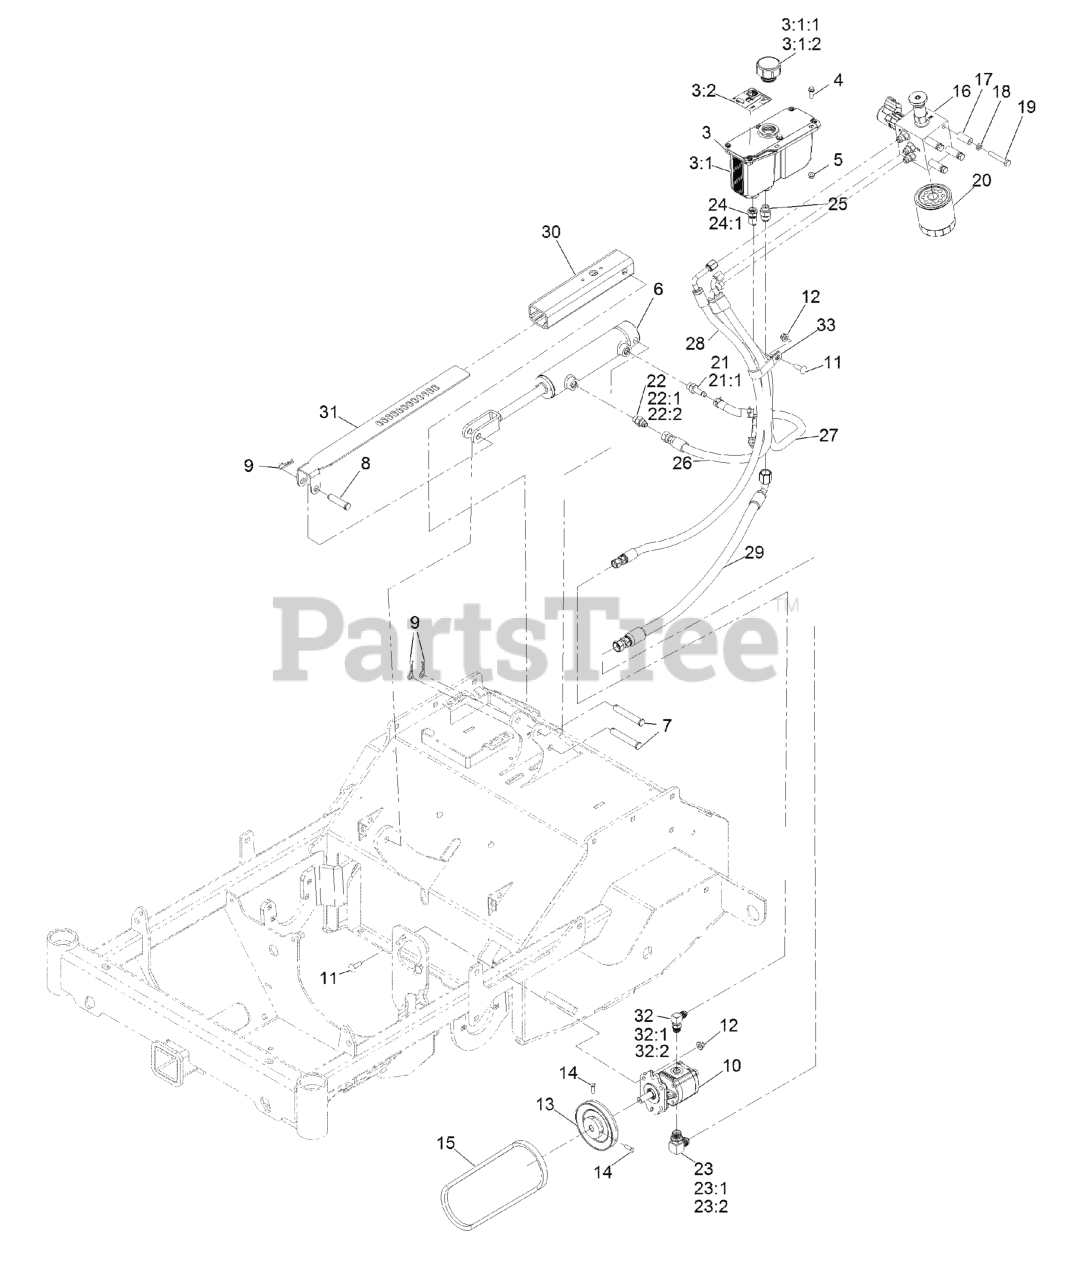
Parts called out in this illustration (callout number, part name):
3	RESERVOIR ASM
3:1	Reservoir-HYD
3:1:1	Cap-Reservoir, HYD
3:1:2	GASKET-CAP
3:2	DECAL-WARNING
4	SCREW-HWH
6	CYLINDER-HYDRAULIC
7	PIN-CLEVIS
8	PIN-CLEVIS
9	PIN-HAIR
10	PUMP-HYDRAULIC
11	SCREW-CARR
12	NUT-HF, NI
14	SCREW-SQH
16	MANIFOLD ASM
18	WASHER-LOCK
19	SCREW-HH
20	FILTER-25 MICRON, BI-DIRECTIONAL
21	ADAPTER-STRAIGHT
21:1	O-RING
22	FITTING-STRAIGHT
22:1	BOSS O-RING
23	FITTING-90 DEG
24	FITTING-BARBED, 45 DEG
24:1	O-RING
25	FITTING-STR
26	HYDRAULIC HOSE ASM
27	HYDRAULIC HOSE ASM
28	HYDRAULIC HOSE ASM
29	HYDRAULIC HOSE ASM
30	HOUSING-DEPTH CONTROL
31	BRACKET-DEPTH CONTROL
32	FITTING-90 DEG
32:1	BOSS O-RING
33	Clamp-R, Double
